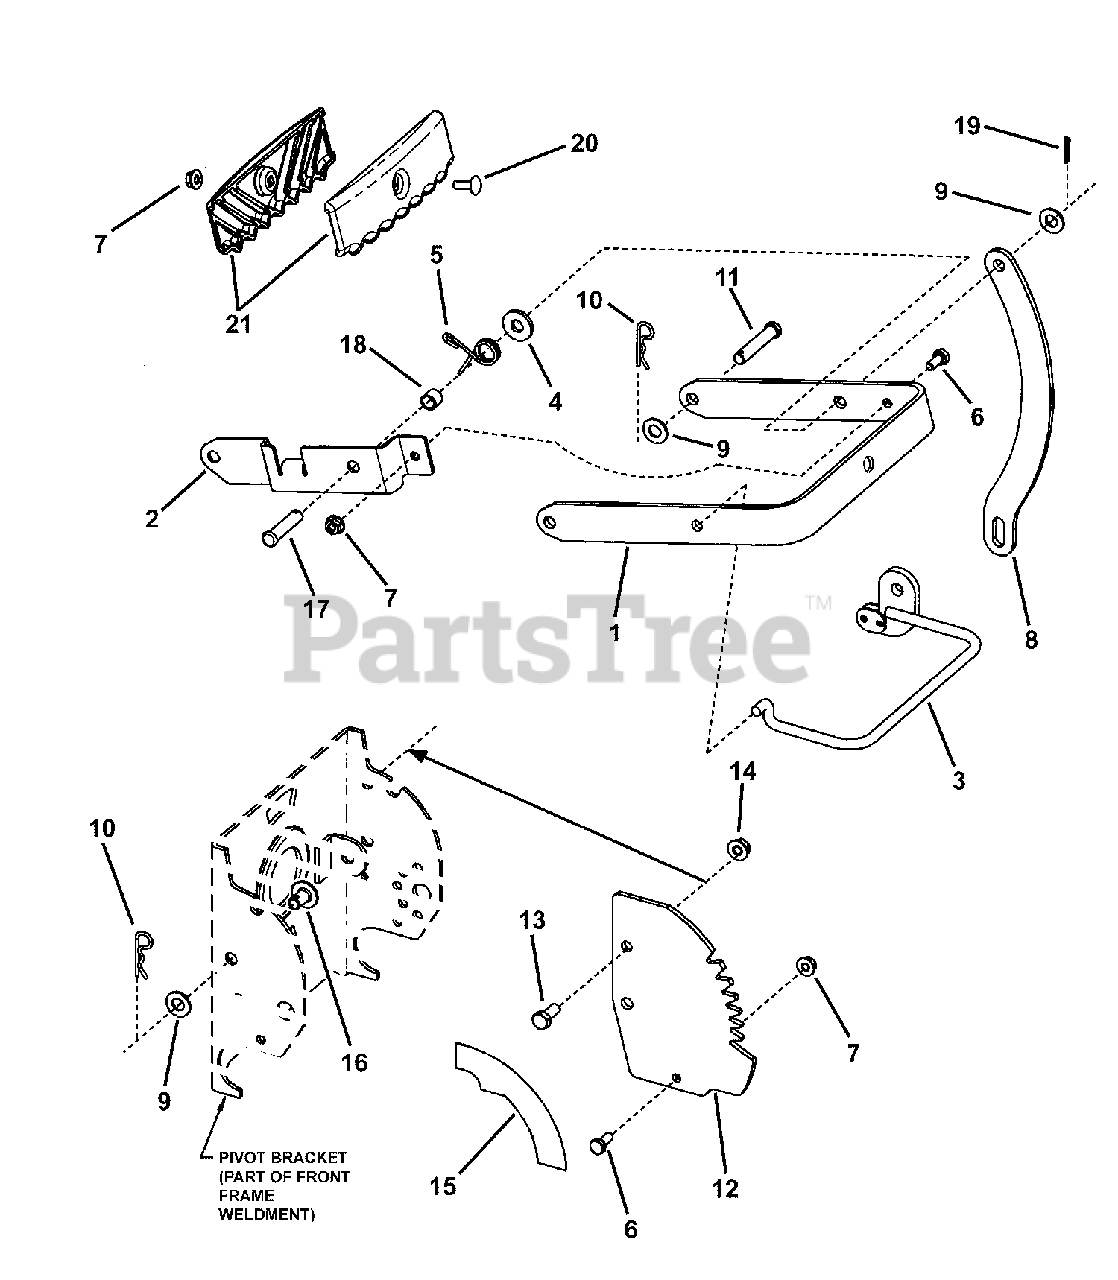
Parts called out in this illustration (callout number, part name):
1	HANDLE, Deck Lift
2	BRACKET, Pivot Support
3	WELDMENT, Deck Lift Handle
4	WASHER - Slipper
5	SPRING, Torsion
6	SCREW, 1/4-20 x 5/8" Hex Head Cap, GR5
7	NUT, 1/4-20 Hex Flange Lock
8	BAR, Deck Lift
9	WASHER, 3/8" SAE Flat
10	HAIR PIN, 3/32 x 1-1/2"
11	PIN, 3/8 x 2" Clevis
12	DETENT, Lift Handle
13	SCREW, 5/16-18 x 3/4" Hex Head Cap, GR5
14	NUT, 5/16-18 Hex Flange Lock, GR5
15	DECAL, Deck Position
16	PIN.38 x .5 Large Head Clevis
17	PIN, 3/8 x 1-5/8" Clevis
18	SPACER, Deck Lift
19	PIN, 3/32 x 3/4" Cotter
20	BOLT, 1/4-20 x 3/4 Short Neck Carriage, GR5
21	GRIP, Deck Lift
